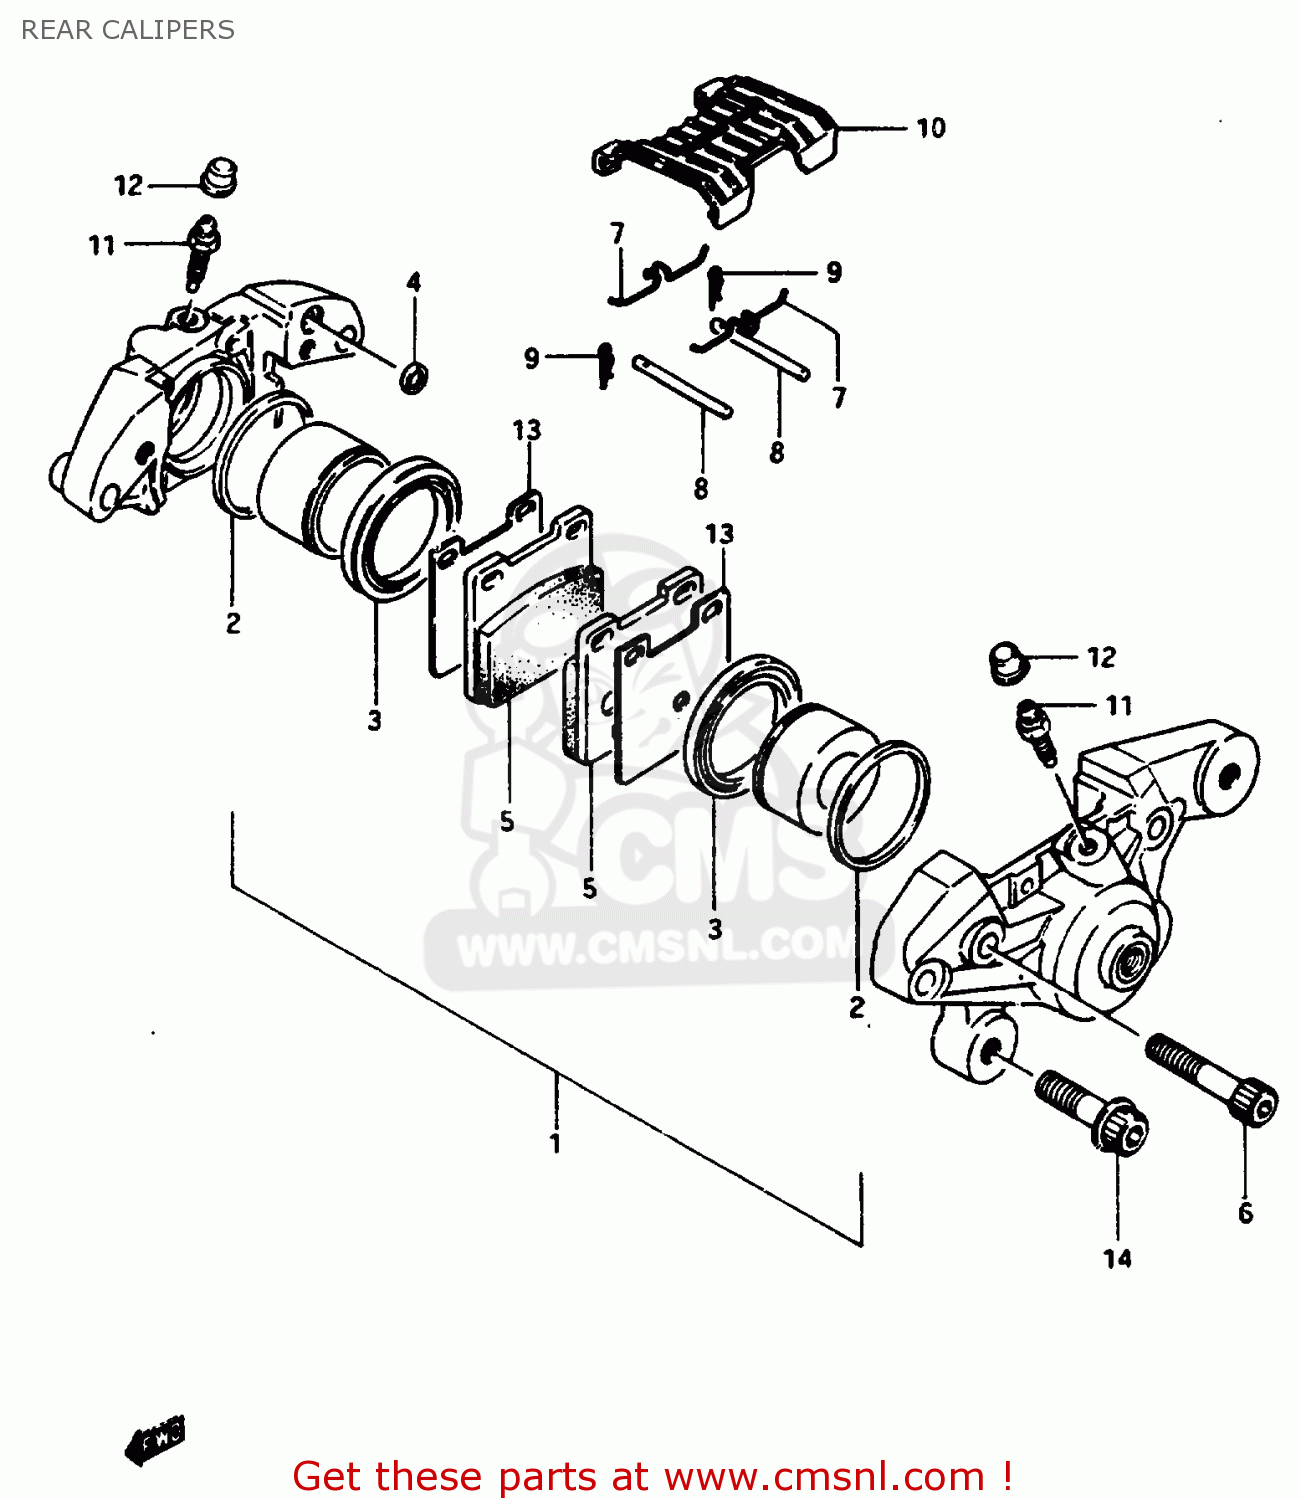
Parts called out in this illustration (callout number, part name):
1	PISTON SET
2	SEAL,PISTON
3	BOOT,PISTON
4	SEAL,JOINT
5	PAD,BRAKE
6	BOLT,CALIPER
7	SPRING
8	PIN,PAD
9	CLIP,PAD PIN
10	COVER,CALIPER
11	BLEEDER
12	CAP,BREATHER
13	SHIM,PAD
14	BOLT 10X28
